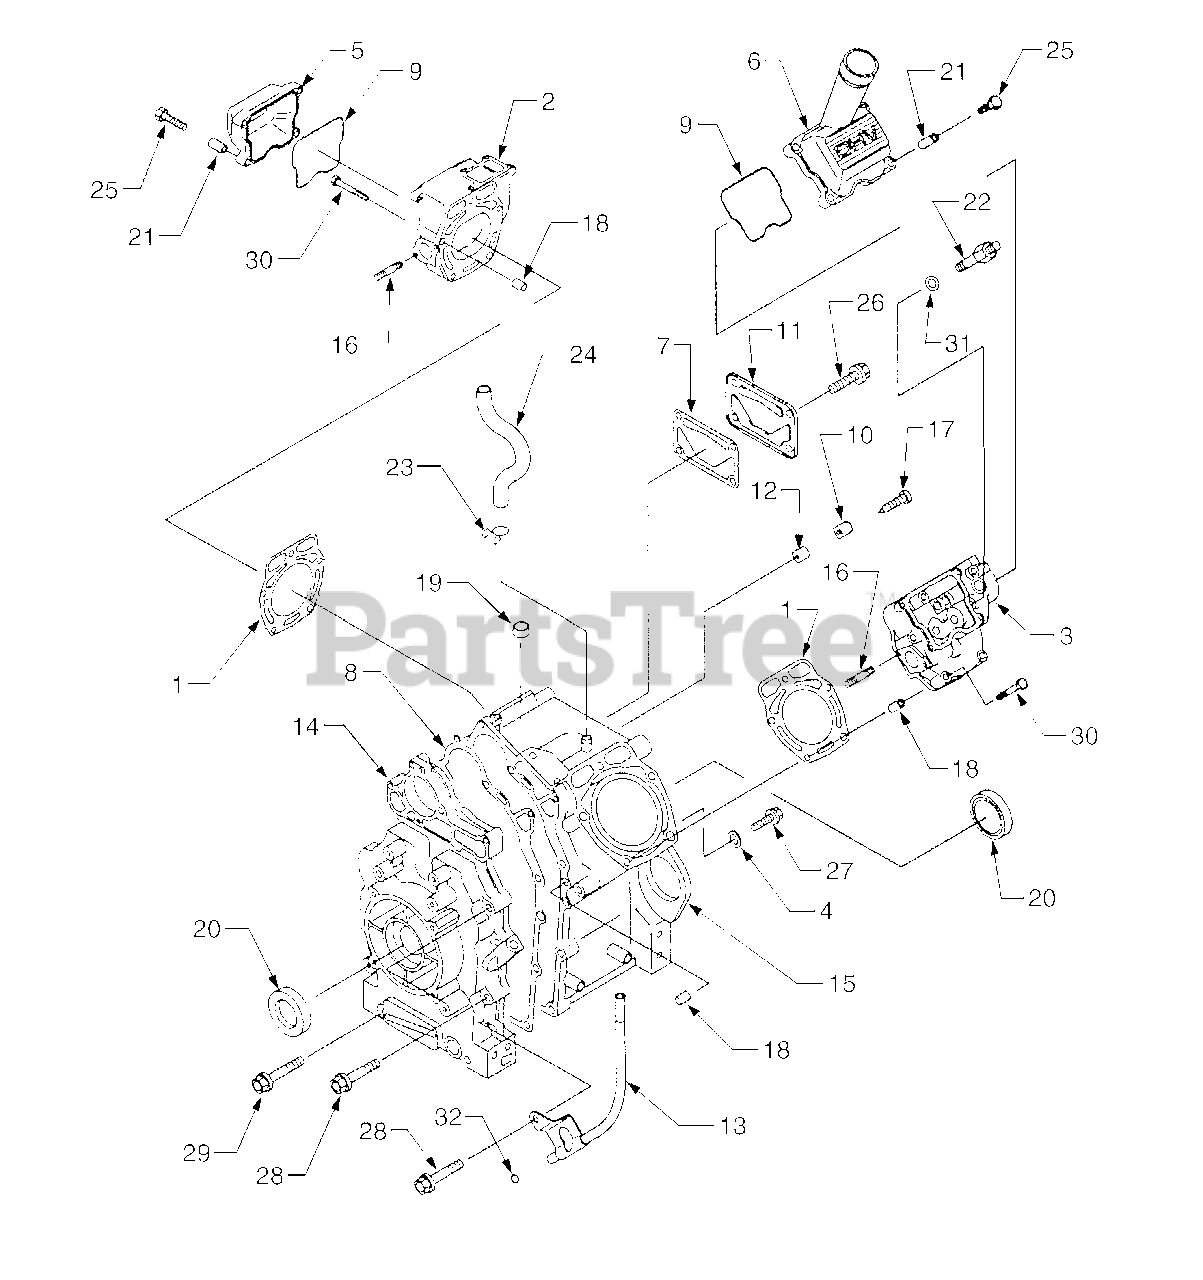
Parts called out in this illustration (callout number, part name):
2	Head, Complete Cylinder
3	Head, Complete Cylinder
6	Cover, Valve w/Oil Fill
7	Gasket, Cover
8	Gasket, Crankcase Cover
9	Gasket, Valve Cover
13	Pipe, Oil Gauge
14	Cover, Crankcase
15	Crankcase Complete
18	Pin, Dowel, M10 x 8.2 x 14
20	Seal, Oil
25	Bolt, Flanged, M6 x 25
26	Bolt, Flanged, M8 x 16
27	Bolt, Flanged, M8 x 12
28	Bolt, Flanged, M8 x 45
29	Bolt, Flanged, M8 x 60
30	Bolt, Flanged, M8 x 65
31	Washer, Plain, 8MM
32	O-Ring, 10MM
